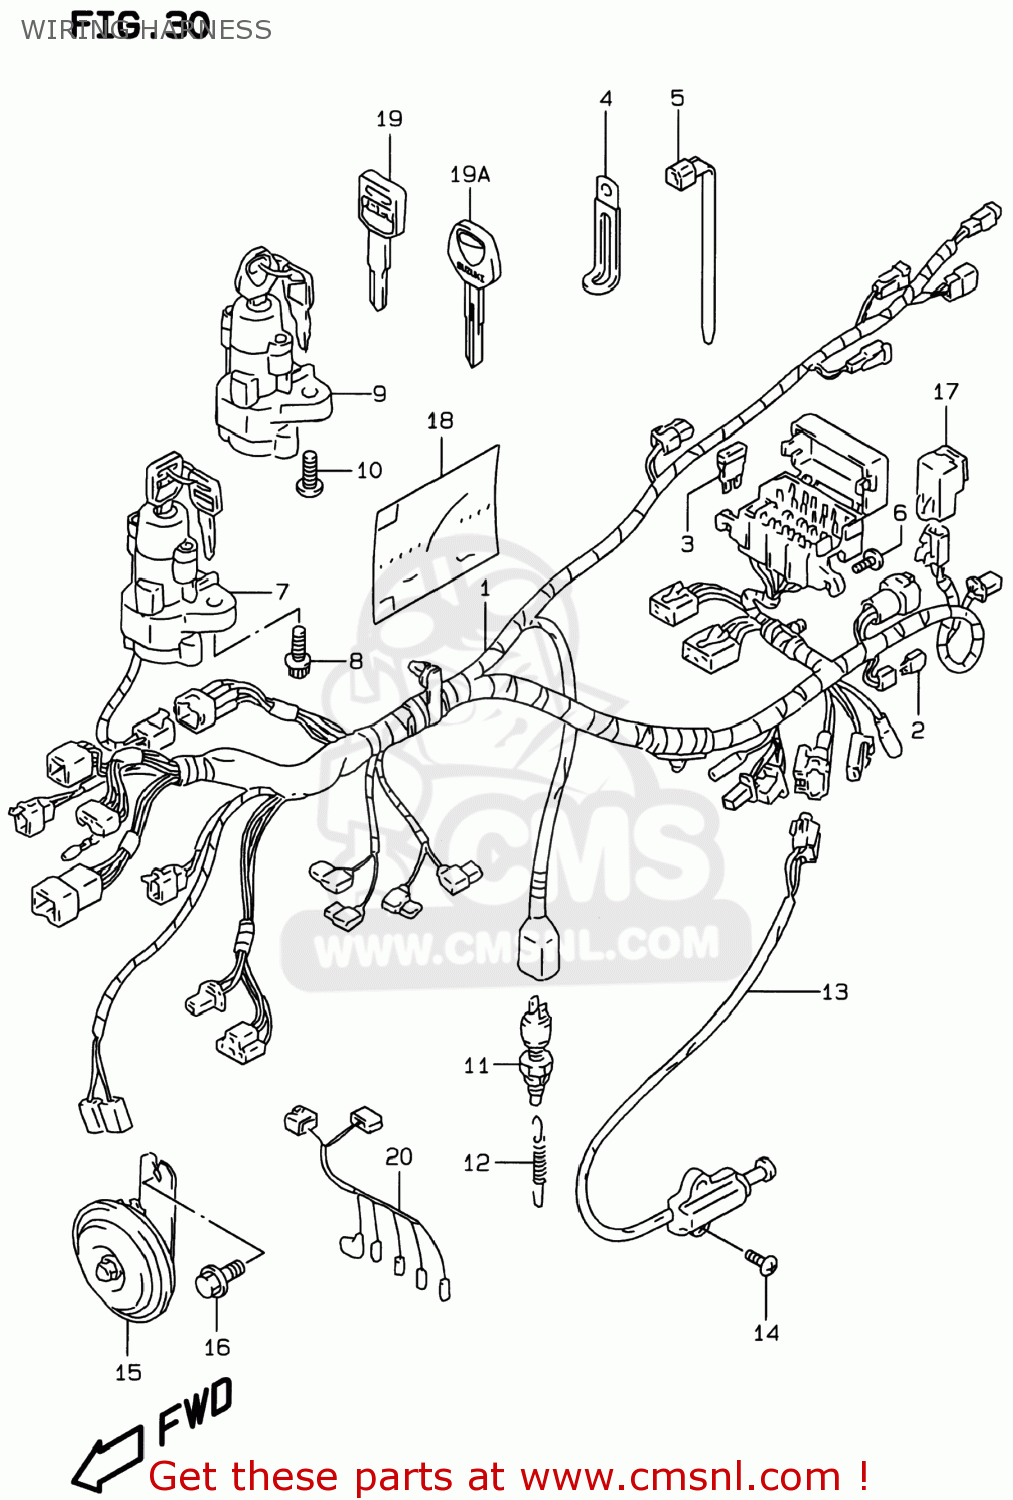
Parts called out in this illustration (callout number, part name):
1	HARNESS,WIRING
2	DIODE(STANLEY DE8804)
3	FUSE(10A)
4	CLAMP(L:65)
5	CLAMP(L:95)
6	SCREW 6X12
7	LOCK ASSEMBLY,STEERING
8	BOLT M8X20
9	LOCK ASSY,STEERING
10	BOLT(8X20)
11	SWITCH ASSY,STOP LAMP
12	SPRING
13	SWITCH ASSY,SIDE STAND
14	SCREW
15	HORN ASSEMBLY,LOW PITCH
16	BOLT
17	RELAY ASSY
18	COVER,WIRING HARNESS
19	KEY,BLANK
19A	KEY,BLANK
20	WIRE,CARB HEATER LEAD
